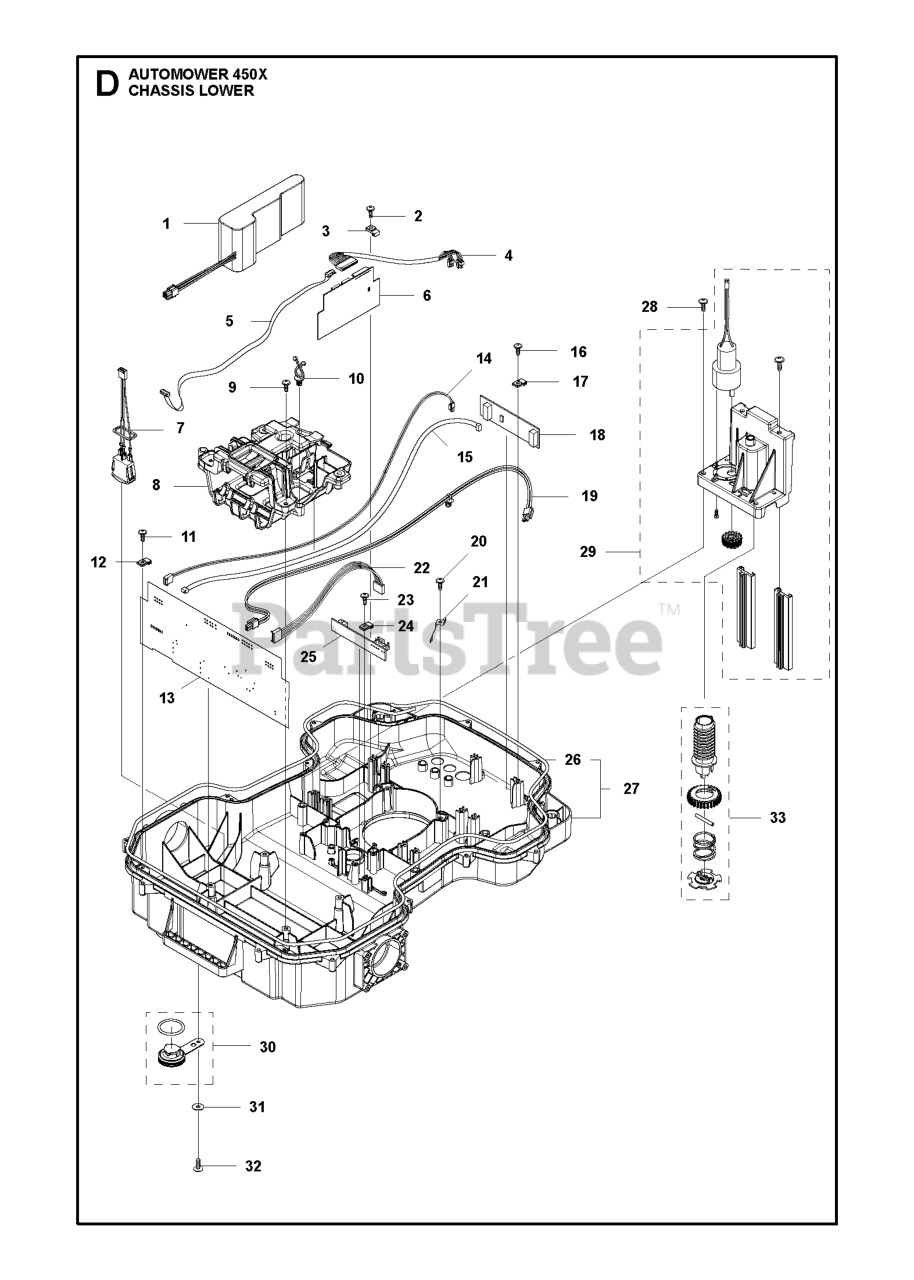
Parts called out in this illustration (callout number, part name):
1	BATTERY 588146401 PACKED
2	SCREW 14MM
3	CLAMP PCB
4	LOOM ULTRA SONIC EXTENSION
5	LOOM AUX
6	PRINTED CIRCUIT ASSY ULTRASONI
7	LOOM ON/ OFF
8	HOLDER BATTERY
9	SCREW ITXPANT
10	HOLDER TWIST LOCK
11	SCREW 14MM
12	CLAMP PCB
13	PRINTED CIRCUIT ASSY PCBA MAIN
14	WIRING ASSY LED LIGHT EXTENSIO
15	LOOM LOOP SENSOR
16	SCREW 14MM
17	CLAMP PCB
18	PRINTED CIRCUIT ASSY LOOP SENS
19	LOOM CHARGING LINK HIGH CHARGI
20	SCREW 14MM
21	SPRING GUIDE HEIGHT ADJUSTMENT
22	LOOM HEIGHT ADJUSTMENT
23	SCREW 14MM
24	CLAMP PCB
25	PRINTED CIRCUIT ASSY PCBA CUTT
26	SEALING STRIP
27	CHASSIS KIT LOWER
28	SCREW 14MM
29	MOTOR ASSY HEIGHT MOTOR
30	PLUG KIT
31	WASHER
32	SCREW ITXPANT
33	SCREW KIT
